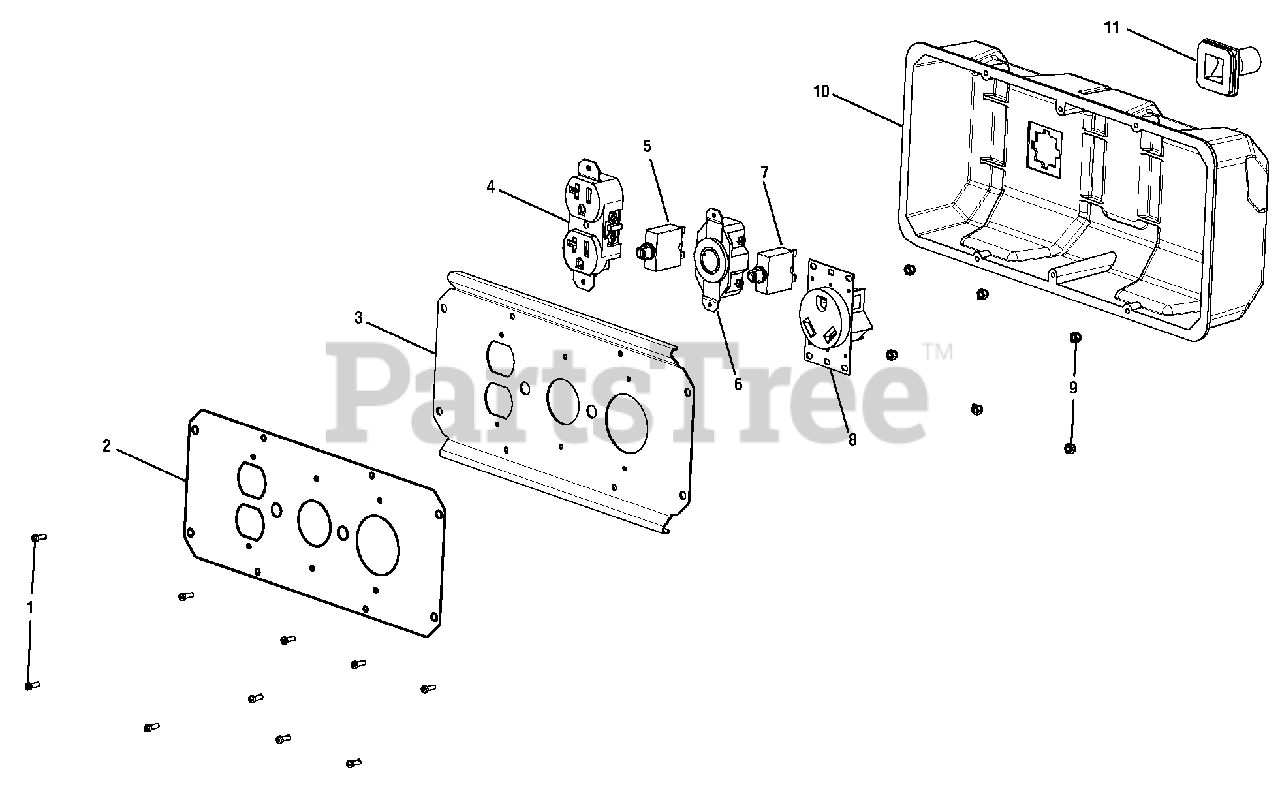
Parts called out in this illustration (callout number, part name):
1	Screw (6-20 x .38 in.)
2	Control Panel Label
3	Control Panel Faceplate
4	120 Volt Duplex Receptacle
5	Circuit Breaker (20A)
6	120 Volt Receptacle (30A)
7	Circuit Breaker (25A)
8	120 Volt RV Receptacle (30A)
9	Nut (6-32)
10	Control Box (Back Panel)
11	Rubber Sleeve
